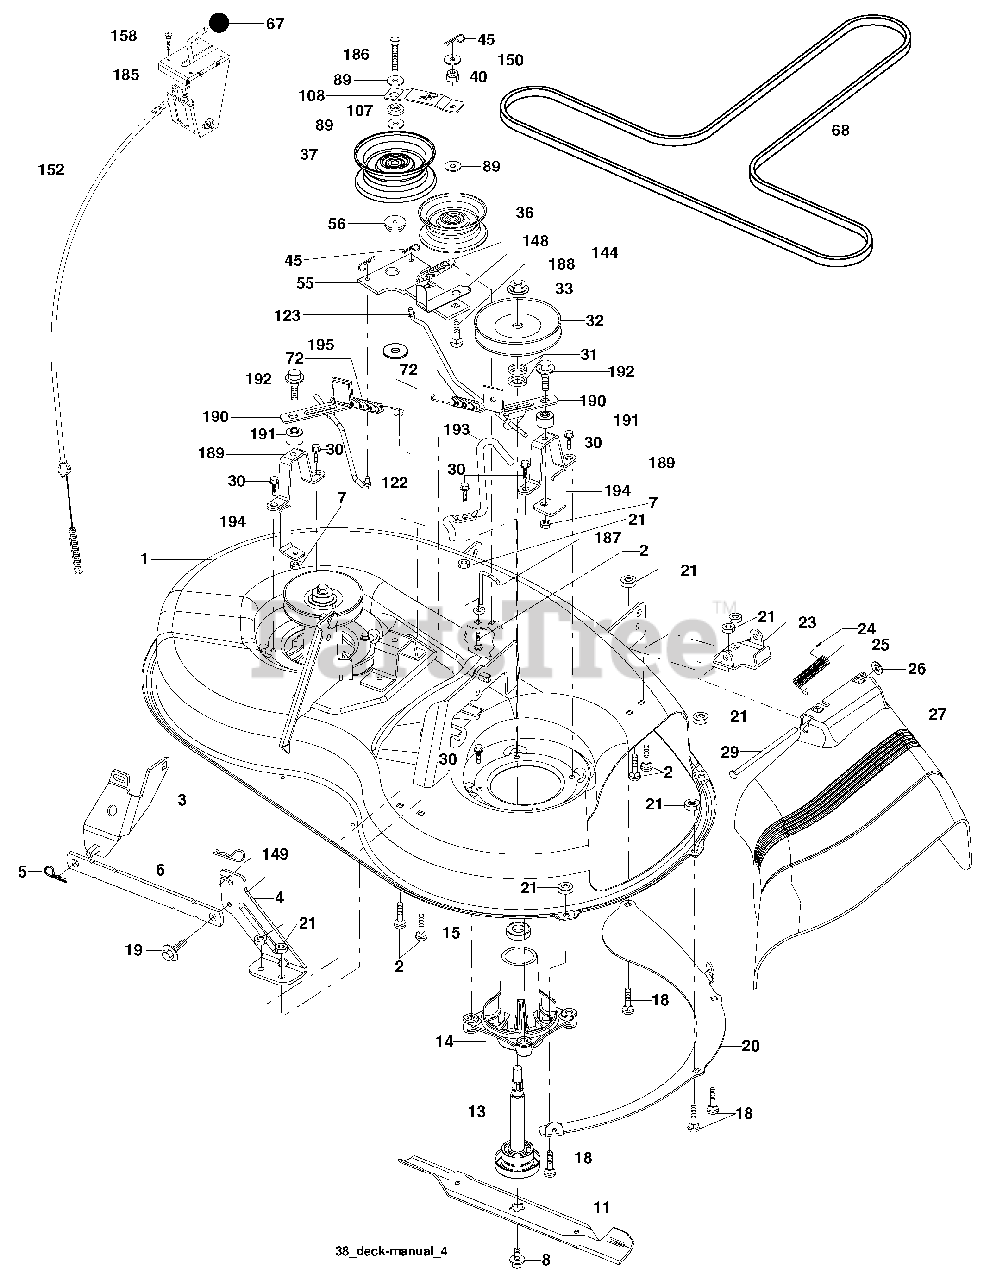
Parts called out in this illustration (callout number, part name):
1	Mower Housing Assembly
2	Bolt Carriage 5/16-18 x 3/4
3	Bracket Asm Fr. Sway Bar
4	Bracket Deck Sway Bar 38"/42"
5	Retainer Spring
6	Bar Sway Deck
7	Nut Lock Hex W/Ins 5/16-18 UNC
8	Bolt Washer Asm 7/16-20 UNF
11	Blade Mower
13	Shaft Assembly, Mandrel, Vented
14	Housing, Mandrel, Vented
15	Bearing, Ball, Mandrel
18	Bolt RDHD SQNK 5/16-18 x 5/8
19	Bolt, Shoulder
20	Baffle Vortex Front
21	Nut
23	Bracket, Mower Deflector
24	Cap, Sleeve
25	Spring, Torsion, Deflector
26	Nut, Push
27	Shield, Deflector
29	Rod, Hinge
30	Screw Thdrol.
31	Washer, Spacer
32	Pulley, Mandrel
33	Nut, Toplock
36	Pulley, Idler, Flat
37	Pulley Idler Flat
40	Nut, Crownlock 3/8-16 unc
45	Retainer
55	Idler Arm Assembly
56	Spacer, Retainer
67	Knob
68	V-Belt, 38" Mower
72	Spring Brake Return
89	Washer 13/32 x 13/16 x 11 Ga.
107	Spacer Retainer
108	Stiffener, Idler Arm
122	Linkage Brake RH
123	Linkage Brake LH
144	Lee[er Be;t Od;er Temsopm
148	Spring Return Idler
149	Retainer Spring Yellow
150	Washer 9/32 x 3/4 x 16 Ga.
152	Clutch Cable 38"/46"
158	Screw Hex Thd Cut 1/4-20 x 1/2
185	Head Asm Cable Clutch
186	Screw HXWSH THDR 3/8-16 x 2 3/4
187	Keeper Belt Front
188	Bolt Carriate Idler
189	Brake Stand
190	Brake Asm
191	Brake Spacer
192	Bolt/Washer Asm 5/16-18
193	Keeper Belt RH Mandrel
194	Brake Guard
195	Washer 13/32 x 2 x 10 Ga.
195	Mandrel Assembly
195	Replacement Mower, Complete
195	Brake Assembly
